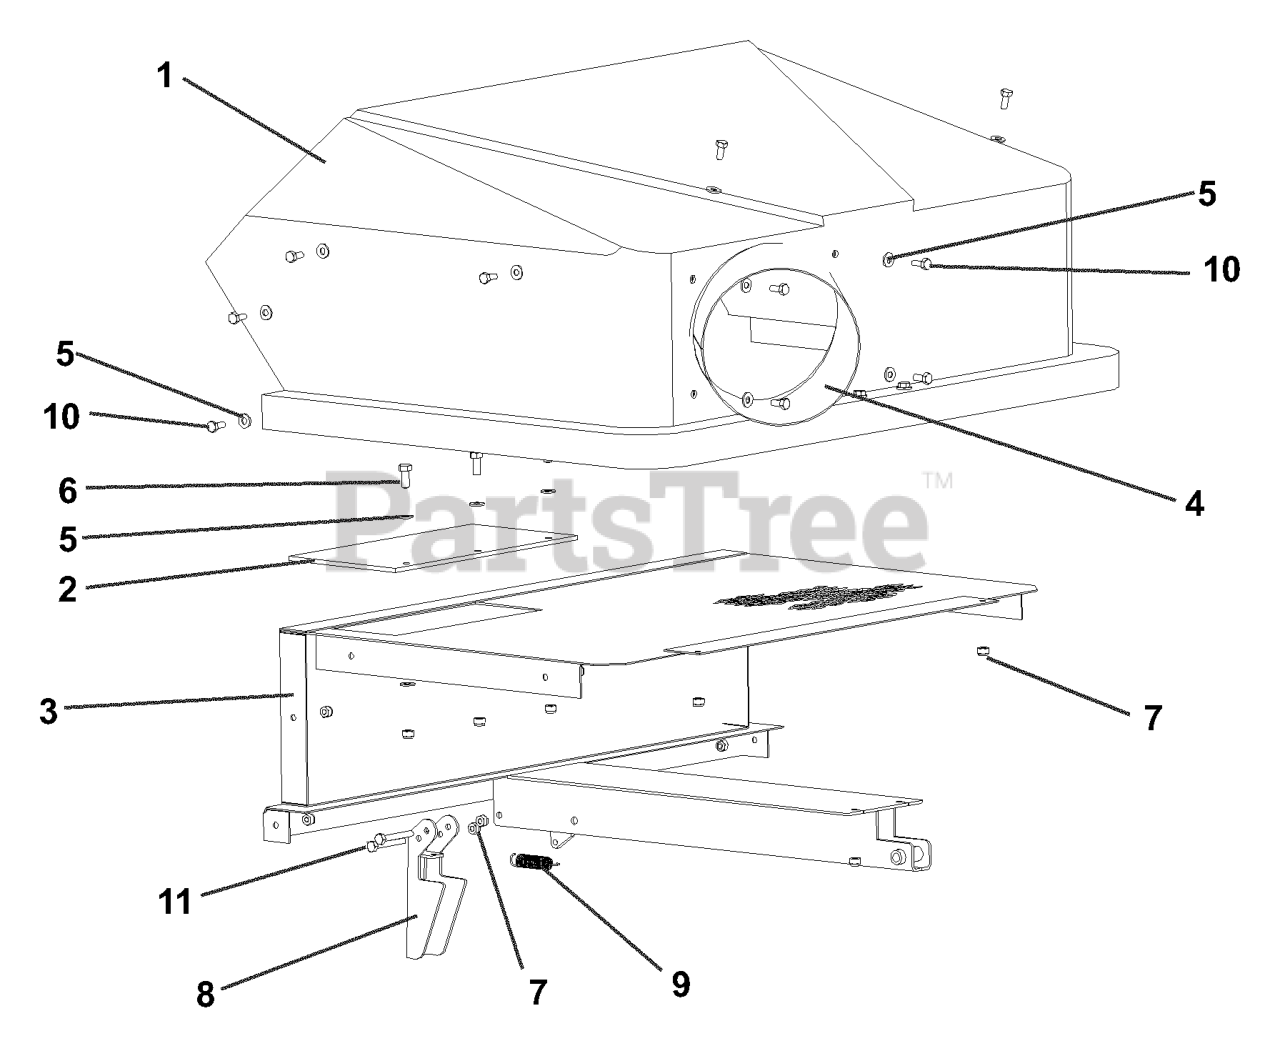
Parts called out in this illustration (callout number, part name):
1	MOLDED TOP
2	RUBBER FLAP
3	TOP INSERT
4	BLOWER HOUSING INLET
5	Washer, Flat, 1/4"
6	Bolt, Hex, 1/4"-20 x 3/4", Gd. 5
7	Nut, Hex, Nylon Lock, 1/4"-20
8	LATCH - CZ9
9	SPRING, TRIP LEVER
10	Bolt, Hex, 1/4"-20 x 5/8"
11	BOLT 1/4-20 X 2"
